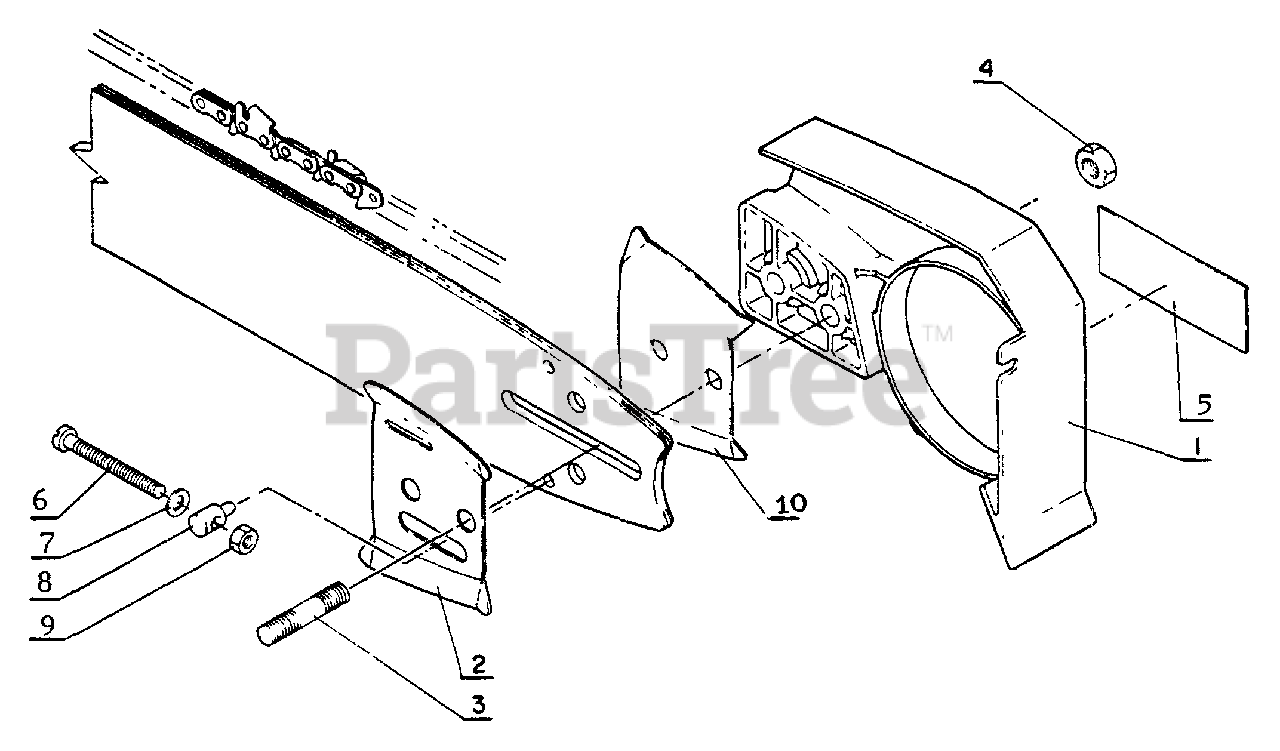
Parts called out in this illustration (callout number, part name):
1	GUARD, SPROCKET
2	PLATE, GUIDE - INNER
3	STUD, GUIDE BAR
4	NUT - FLANGE
5	LABEL - ECHO
6	SCREW, TENSIONER
7	WASHER - 5
8	TENSIONER, CHAIN
9	LOCKNUT - 5
10	PLATE, GUIDE - OUTER
